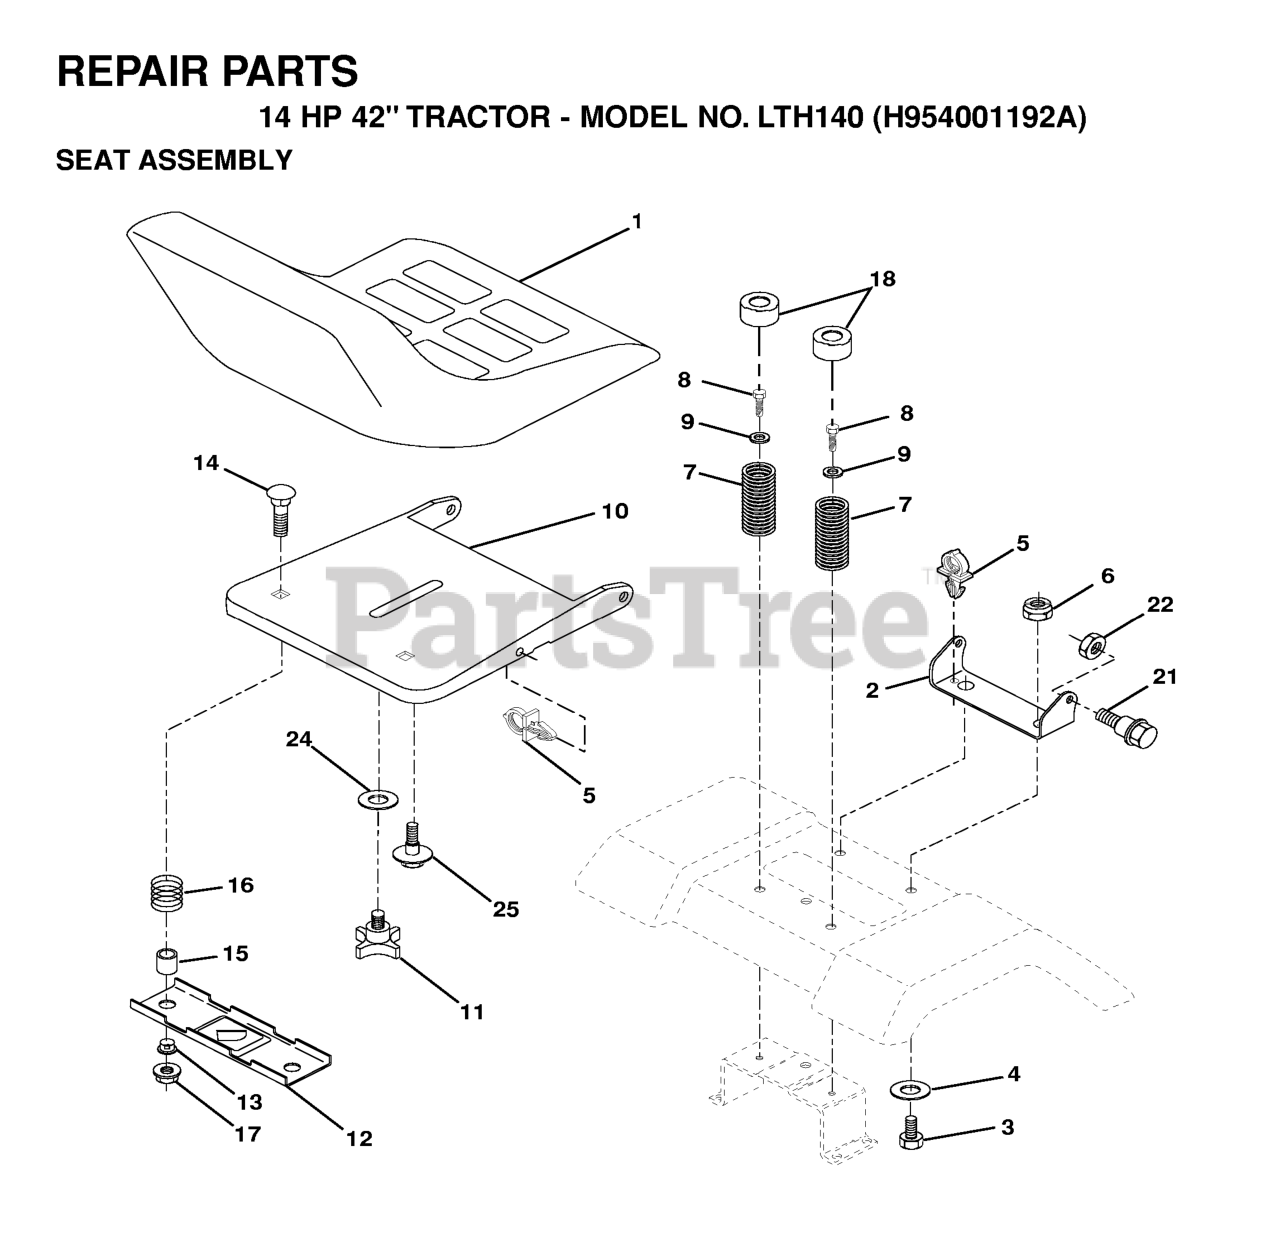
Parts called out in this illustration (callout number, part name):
1	SEAT
2	SEAT PIVOT BRKT
3	BOLT
6	NUT
7	SPRING COMPRESSION
8	SCREW GTV
9	WASHER
10	SEAT PAN
11	KNOB 1/2" YT
12	BRKT SWITCH
14	Bolt Rdhd. Sht. Nk 1/4-20 x 1-3/8
15	SPACER SPLIT 28X.96
17	NUT T
18	CAP SPRING
21	BOLT.SHOULDER.5/16-18
22	NUT.71038.31-18.HEX.NYLOCK
25	BOLT,SHOULD
